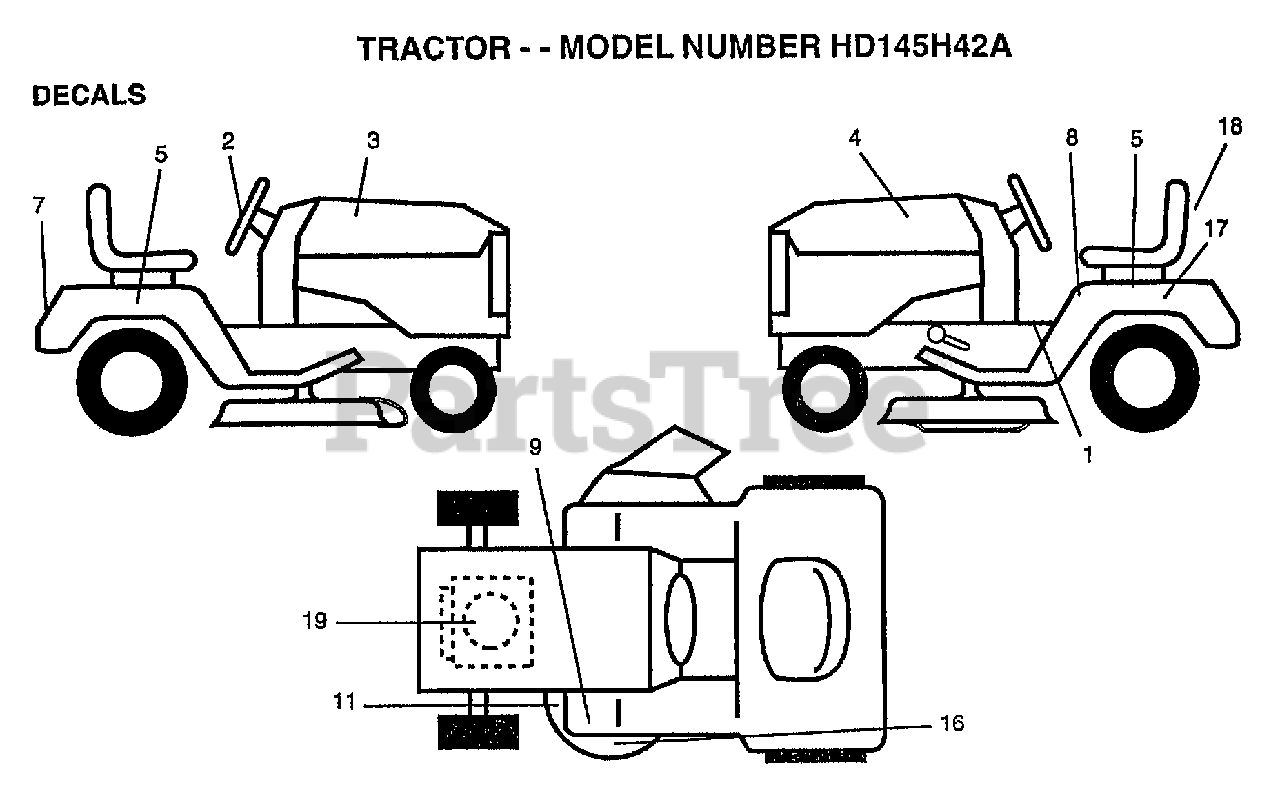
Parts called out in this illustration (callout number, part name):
1	"DECAL-SADDLE,INST"
2	"DECAL WHEEL,STEER"
3	"DECAL-HOOD,RH"
4	"DECAL-HOOD,LH"
5	"DECAL FENDER,SD"
7	"DECAL FENDER,LOGO"
8	"DECAL FENDER,DANG"
9	DECAL CLUT/BRAKE
11	DECAL
16	"DECAL DECK,MULCH"
17	DECAL.BATRY.3-3908
18	"DECAL SEAT,ACC"
19	"DECAL REPLCMT,ENG"
